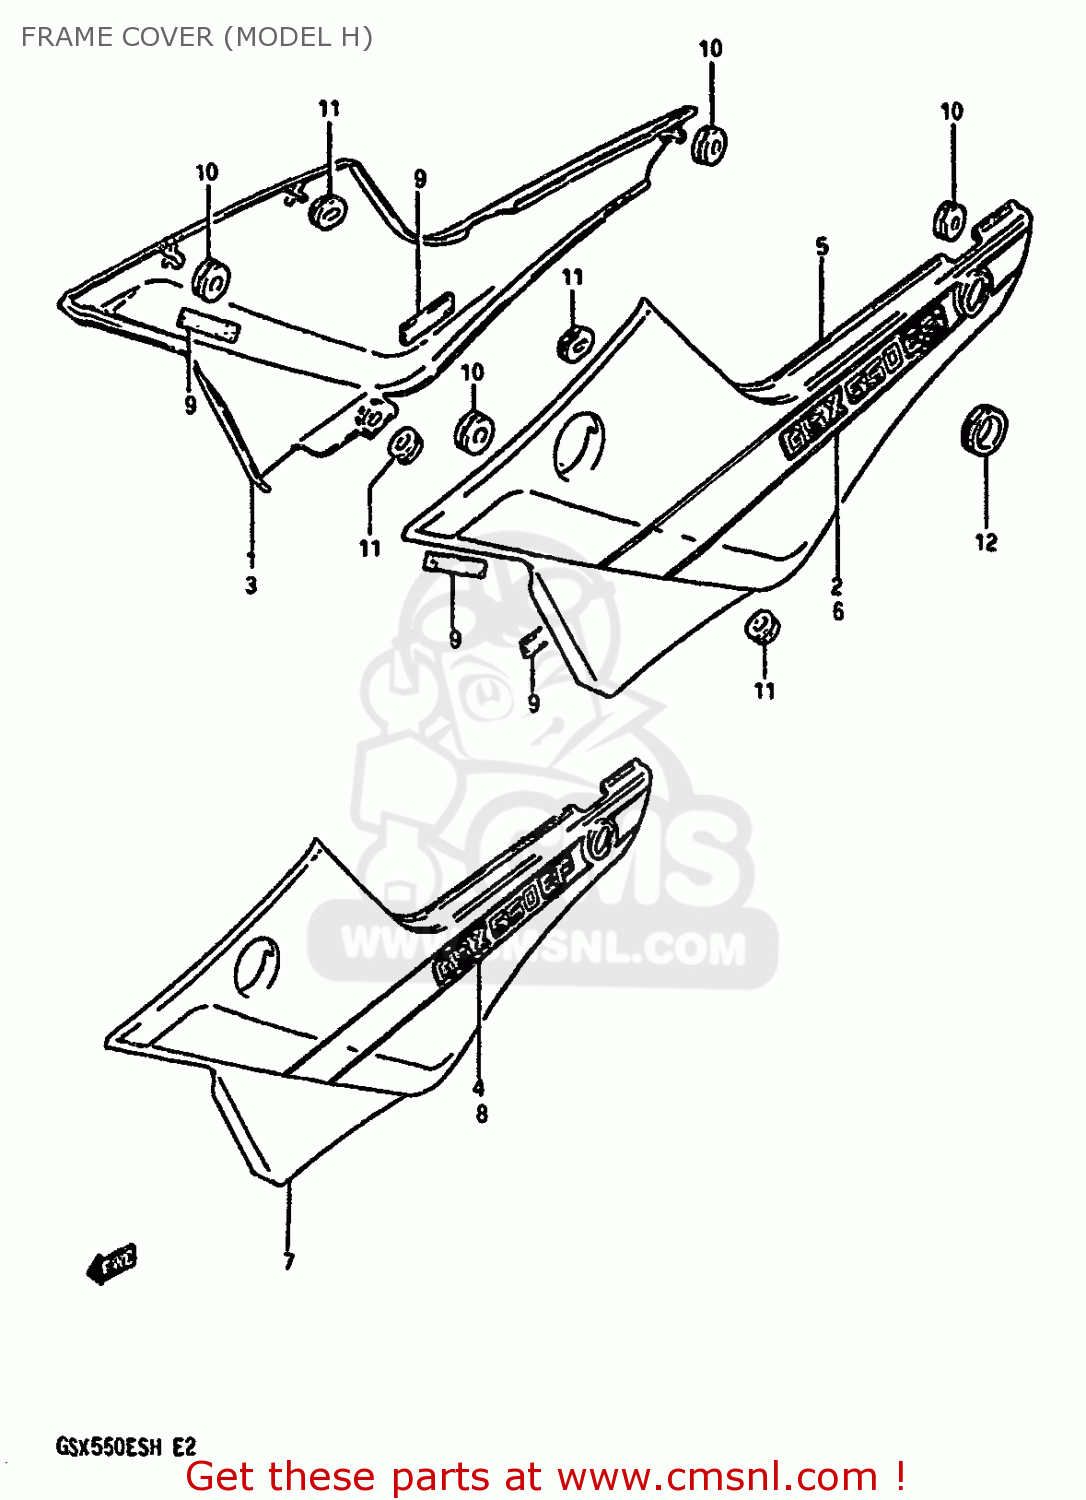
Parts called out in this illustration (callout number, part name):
1	COVER,FRAME RH
2	TAPE SET,FRAME COVER RH
3	COVER,FRAME RH
4	TAPE SET,FRAME COVER RH
5	COVER,FRAME LH
6	TAPE SET,FRAME COVER LH
7	COVER,FRAME LH
8	TAPE SET,FRAME COVER LH
9	RUBBER,FRAME COVER
10	CUSHION
11	CUSHION
12	GROMMET,SEAT LOCK HOLE
